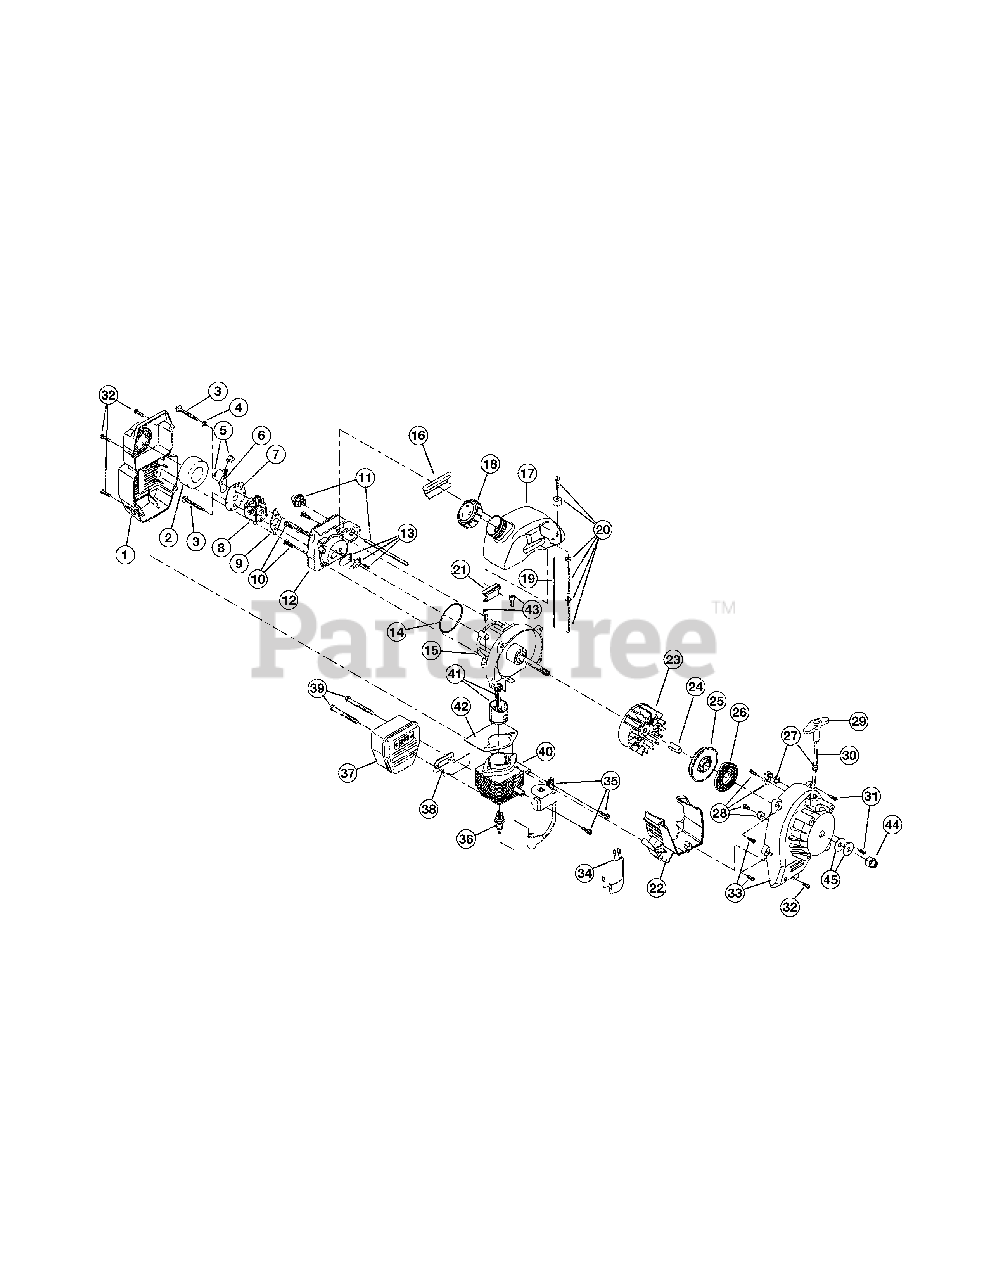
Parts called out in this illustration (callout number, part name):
1	Air Cleaner/Muffler Cover Assembly
2	Air Cleaner Filter
3	Carburetor Mounting Screw
4	Wavey Washer
5	Choke Knob and Screw
6	Choke Lever Assembly
7	Choke Lever and Plate
8	Carburetor Assembly
9	Carburetor Gasket
10	Carb Mount Screw
11	Primer and Hose Assembly
12	Carb Mount Assembly
13	Reed Assembly
14	Carburetor O-Ring
15	Crank Case Service Assembly
16	Rear Mounting Pad
17	Fuel Tank Assembly
18	Fuel Cap Assembly
19	Fuel Return Line
20	Fuel Line Assembly
21	Front Mounting Pad
22	Shroud Extension
23	Flywheel Assembly
24	Spacer
25	Recoil Pulley
26	Recoil Spring
27	Rope Guide
28	Pulley Retainer Assembly
29	Pull Handle
31	Housing Screw
32	Cover Screw
33	Starter Housing Assembly
34	Wire Lead Assembly
35	Module Assembly
36	Spark Plug
37	Muffler Assembly
38	Exhaust Gasket
39	Muffler Mounting Bolt Assembly
40	Cylinder Assembly
41	Piston and Rod Assembly
42	Cylinder Gasket
43	Cylinder Bolt
44	Crankshaft Extension
45	Washer
